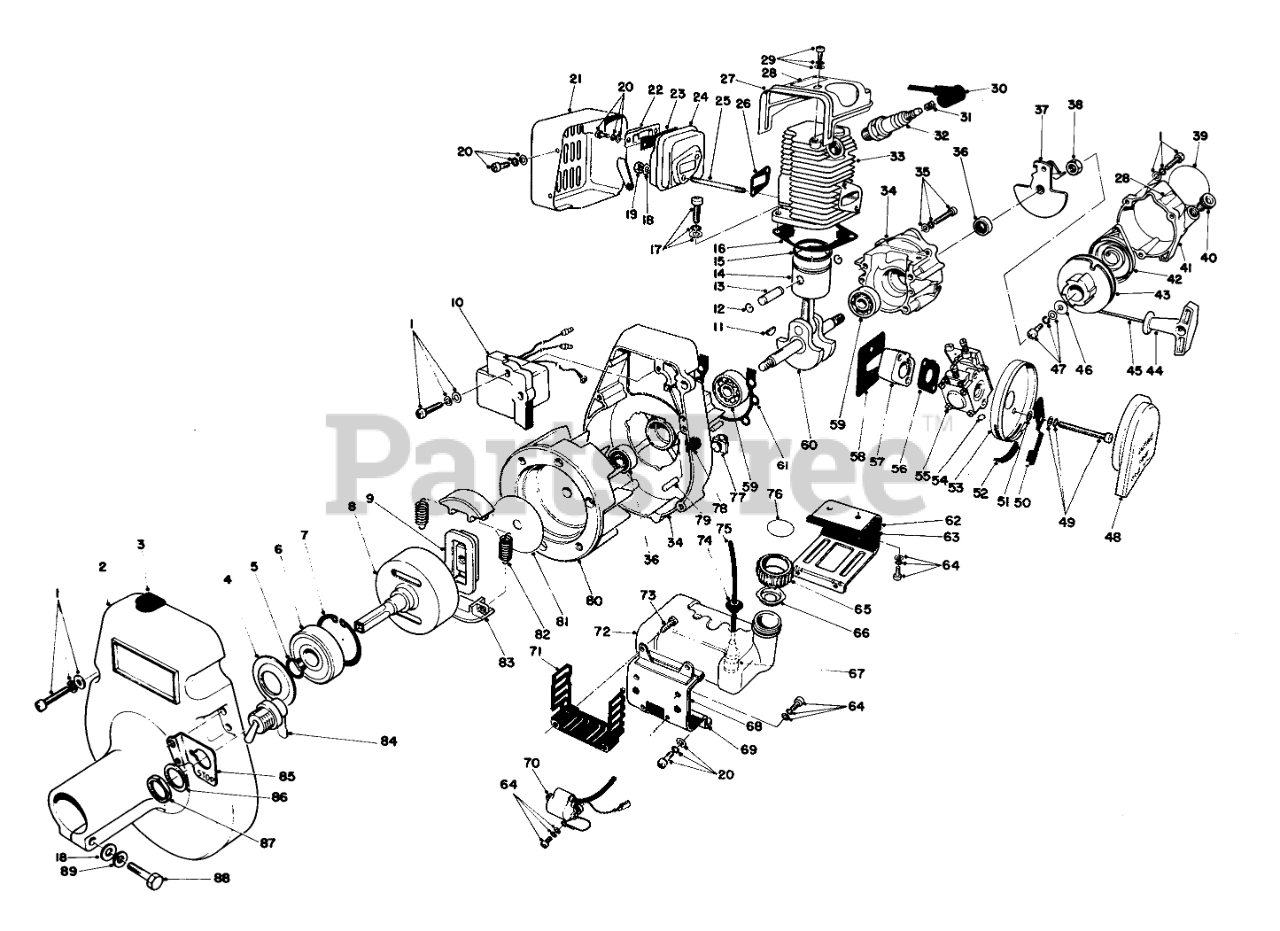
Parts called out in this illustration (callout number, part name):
1	SCREW
2	Fan Cover
4	Stopper
5	Circlip
6	Ball Bearing
7	Circlip
8	Clutch Drum
9	Clutch Boss
10	MODULE CDI-WILLMAR
11	Woodruff Key
12	Circlip, Piston Pin
13	Piston Pin
14	Piston
15	PISTON RING
16	Gasket, Cylinder Base
17	Screw
18	WASHER
19	Locknut
20	SCREW
21	Muffler Cover
22	Lid-Muffler
23	Screen
24	Muffler Body
25	STUD BOLT
26	Gasket, Muffler
27	Cylinder Cover
28	Decal-Hot Surface
29	SCREW
30	Cap-Spark Plug
31	Coil Spring-Plug Cap
33	Cylinder
34	Crankcase Set
35	SCREW
36	Oil Seal
37	Ratchet Assembly
39	Decal
40	Rope Guide
41	Starter Case
42	REWIND SPRING
43	Recoil Drum
44	Starter Handle
45	Rope-Starter
46	WASHER-WILLMAR
47	Screw
48	AIR FILTER
49	SCREW
50	CHOKE SHUTTER
51	CHOKE SHUTTER SPACER
52	Grommet
53	Case-Air Cleaner
54	Clip Fuel Pipe
55	Carburetor Assembly
56	Gasket
57	Insulator
58	INSULATOR GASKET-WILLMAR
59	Bearing
60	Crankshaft Assembly
61	Gasket-Crankcase
62	Bracket-Fuel Tank
63	Cushion
64	Screw
65	Cap-Fuel Tank
66	Check Valve
67	FUEL STRAINER
68	Cushion
69	Bracket-Fuel Tank
70	IGNITION COIL-WILLMAR
71	Dust Filter
72	FUEL TANK
73	Screw
74	GROMMET
75	Fuel Hose
76	Decal Fuel Mix
77	Cord Holder
78	Grommet
79	Knockpin
80	Flywheel
81	Side Plate
82	CLUTCH SPRING
83	CLUTCH SHOE
84	Switch (Incl. Ref. #86 & 87)
85	Bracket-Switch
86	Washer
87	Nut
89	Washer
